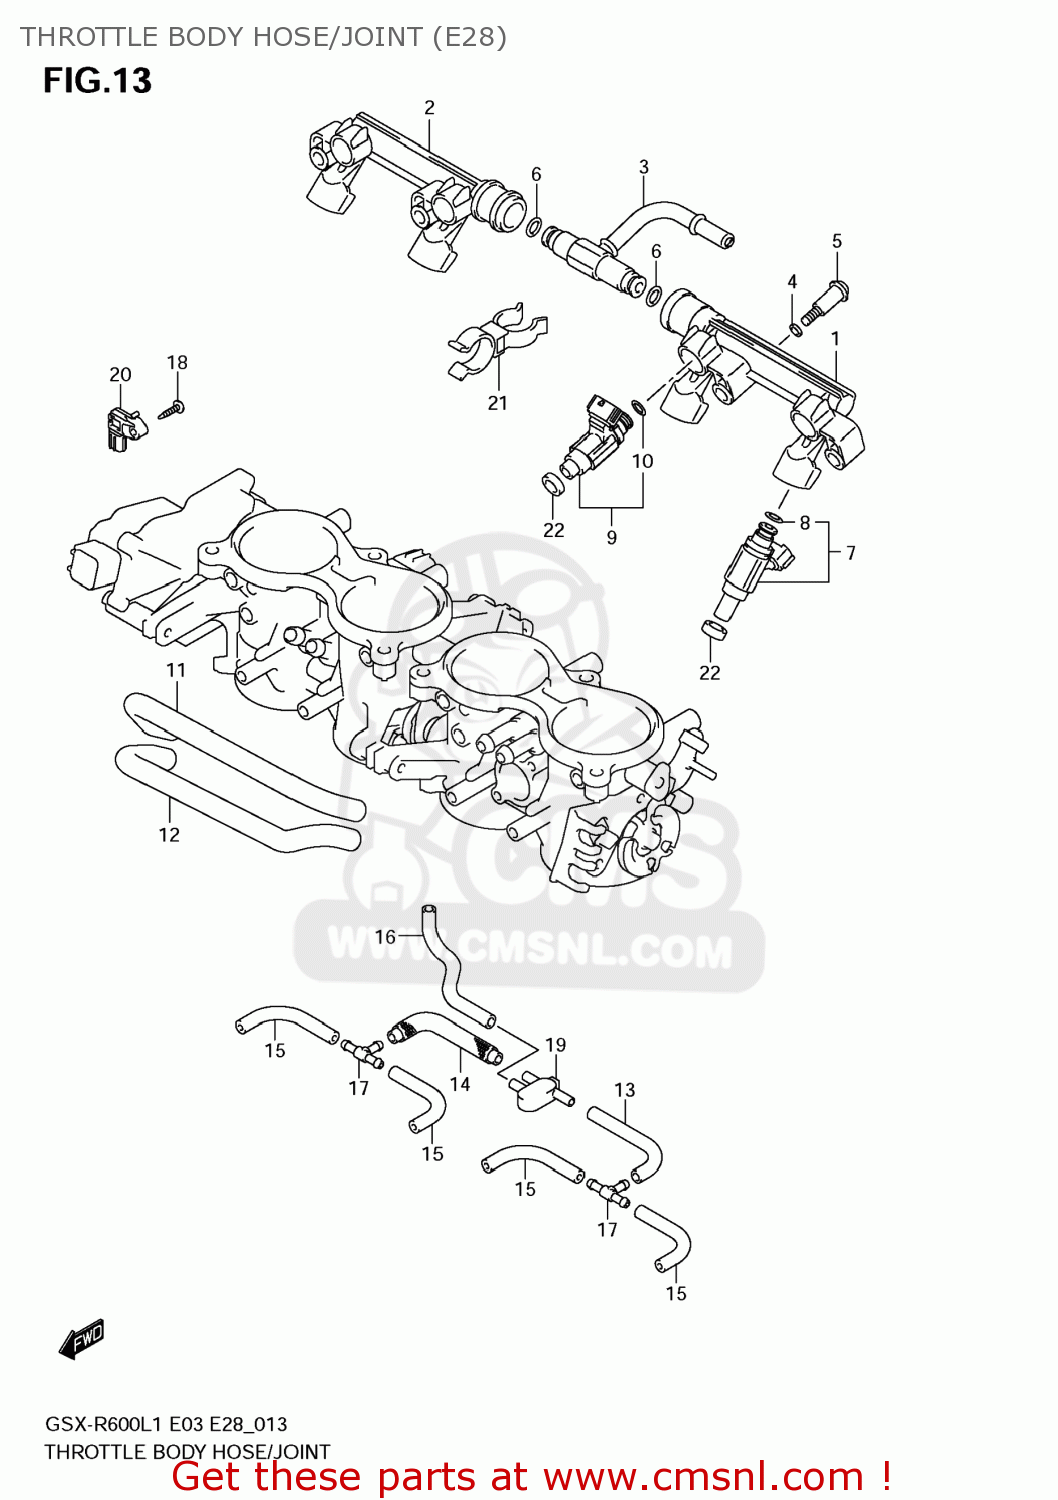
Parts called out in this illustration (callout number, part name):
1	DELIVERY PIPE
2	DELIVERY PIPE
3	NIPPLE ASSY
4	PACKING (NAS)
5	SCREW
6	O RING
7	INJECTOR ASSY
8	O-RING
9	INJECTOR ASSY
10	O-RING
11	HOSE
12	HOSE
13	HOSE
14	HOSE
15	HOSE(L:425)
16	HOSE
17	3WAY,VACUUM HOSE
18	SCREW
19	JOINT
20	SENSOR,BOOST
21	CLAMP
22	SEAL
